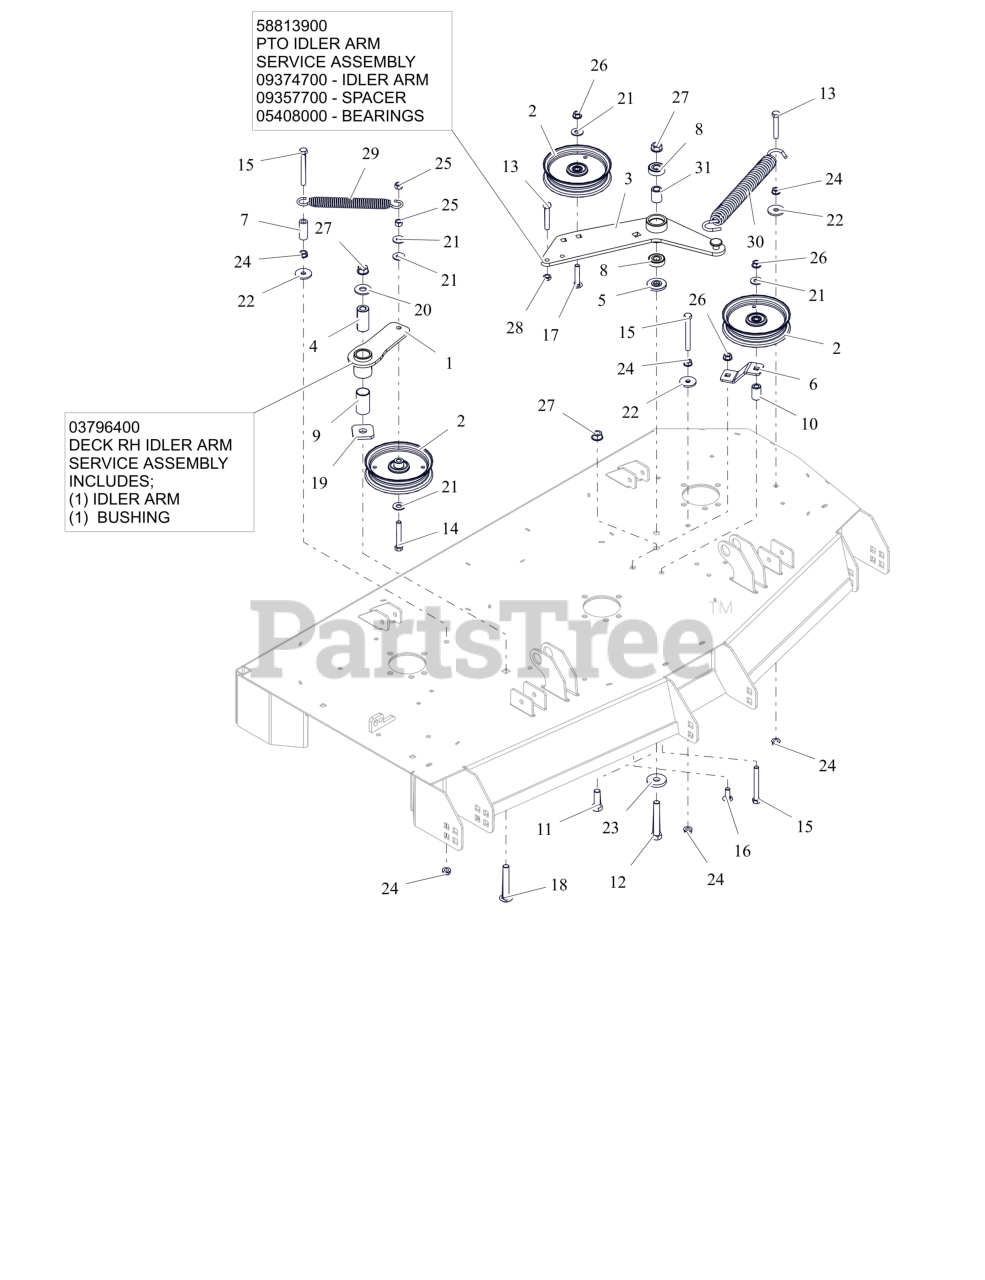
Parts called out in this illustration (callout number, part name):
1	WMT, IDLER ARM - BLACK
1	ASM, IDLER ARM (DECK)
2	IDLER- FLAT - 5.00" X .75"
3	WLDMT, IDLER ARM PT660
3	PTO IDLER ARM
3	SPACER .510 X .867 X 1.1485
3	BRG-BALL .500X1.38X.437
4	BSHG, SPCR .502X.997X2.03 PM
5	SPACER, IDLER ARM
6	PTO FIXED IDLER MTG BRKT -RED
7	HOSE, .38 X 1.65
8	BRG-BALL .500X1.38X.437
9	BSHG, 1.00X1.125X1.937
10	BUSHING, SLV .380X.750X1.190
11	BLT,HEX .50-13X1.50 G5 ZCC
12	BLT,HEX .50-13X3.25 G5 ZCC
13	BLT,HEX .38-16X2.25 G5 ZCC
14	BLT, HEX .38-16X2.50 G5 ZCC
15	BLT, HEX .38-16X3.25 G5 ZCC
16	BLT,RHSSN .38-16X1.00 G5 ZCC
17	BLT,RHSSN.375-16X2.00 G5 ZCC
18	BTL,RHSSN .500-13 X 3.25 G5 ZCC
19	WSHR-FLT .640X1.75X.250
20	WSHR,FLT .563X1.375X.109 ZCC
21	WSHR,FLT .438X1.00X.083 ZCC
22	WSHR,FLT .406X1.375X.135 ZCC
23	WSHR-FL-STL 0.557X1.625X0.25 ZCC
24	NUT, SPNLK-FLG .38-16 G5 ZCC
25	NUT-LK-CTR .38-16 ZC120
26	NUT-LK-CTR-FLG .375-16 GF ZCC
27	NUT-LK-CTR-FLG .500-13 GG ZCC
28	NUT-JAM .375-16 G2 ZCC
29	SPRING- EXTENSION
30	SPRING, EXTENSION
31	SPACER .510 X .867 X 1.1485
